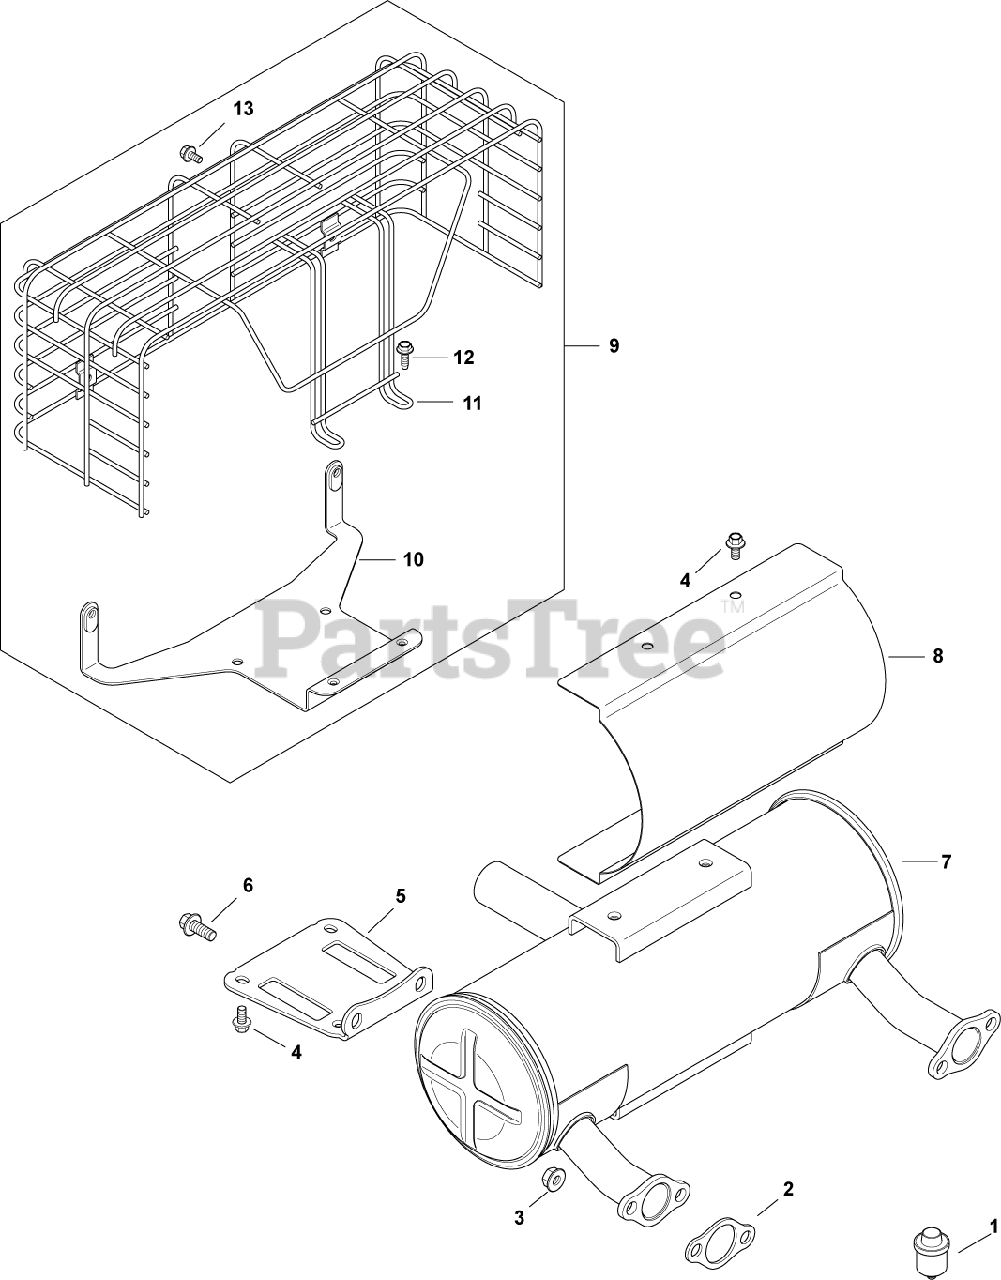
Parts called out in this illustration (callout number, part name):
1	KIT, AIR FILTER SENSOR
2	GASKET, EXHAUST
3	NUT, FLG M8X1.25
4	SCREW, FLG M6X1.0X12
5	BRACKET, MUFFLER
6	SCREW, FLG M8X1.25X20
7	MUFFLER, CENTER/STRAIGHT USE 24 068 131-S
8	SHIELD, HEAT-USE 24 314 50-S
9	KIT, MUFFLER GUARD
10	BRACKET, EXHAUST GUARD
11	GUARD, MUFFLER
12	SCREW,FLG THD FRM M5X0.8X16-(#25086398S)
13	SCREW, HVY FLG M5X.8X10
